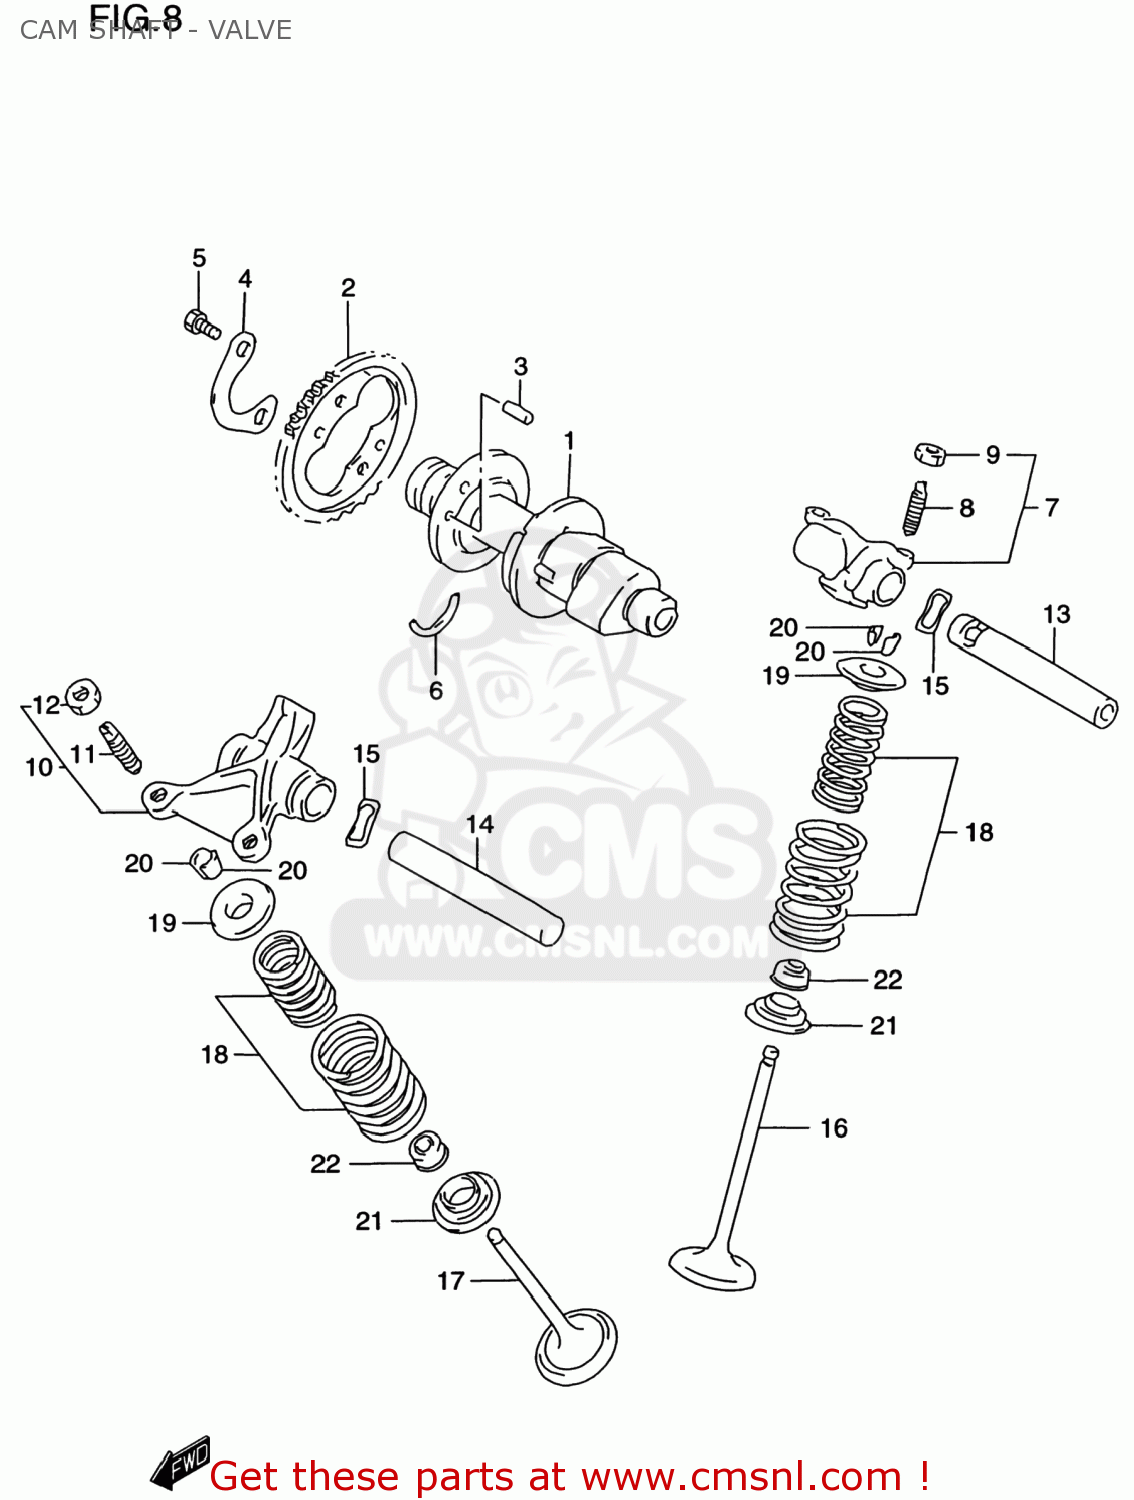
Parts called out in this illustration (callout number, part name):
1	CAMSHAFT
2	SPROCKET,CAMSHAFT(NT:38)
3	PIN(5X8)
4	WASHER,SPROCKET
5	BOLT(6X10.5)
6	C RING
7	ARM,VALVE ROCKER INTAKE
8	SCREW,TAPPET ADJUSTING
9	NUT,ADJUSTING SCREW
10	ARM,VALVE ROCKER EXHAUST
11	SCREW,TAPPET ADJUSTING
12	NUT,ADJUSTING SCREW
13	SHAFT,VALVE ROCKER ARM INTAKE
14	SHAFT,VALVE ROCKER ARM EXHAUST
15	WASHER
16	VALVE,INTAKE
17	VALVE,EXHAUST
18	SPRING SET,VALVE
19	RETAINER,VALVE SPRING
20	COTTER,VALVE
21	SEAT,VALVE SPRING
22	SEAL,OIL(5.5X11X8.2)
